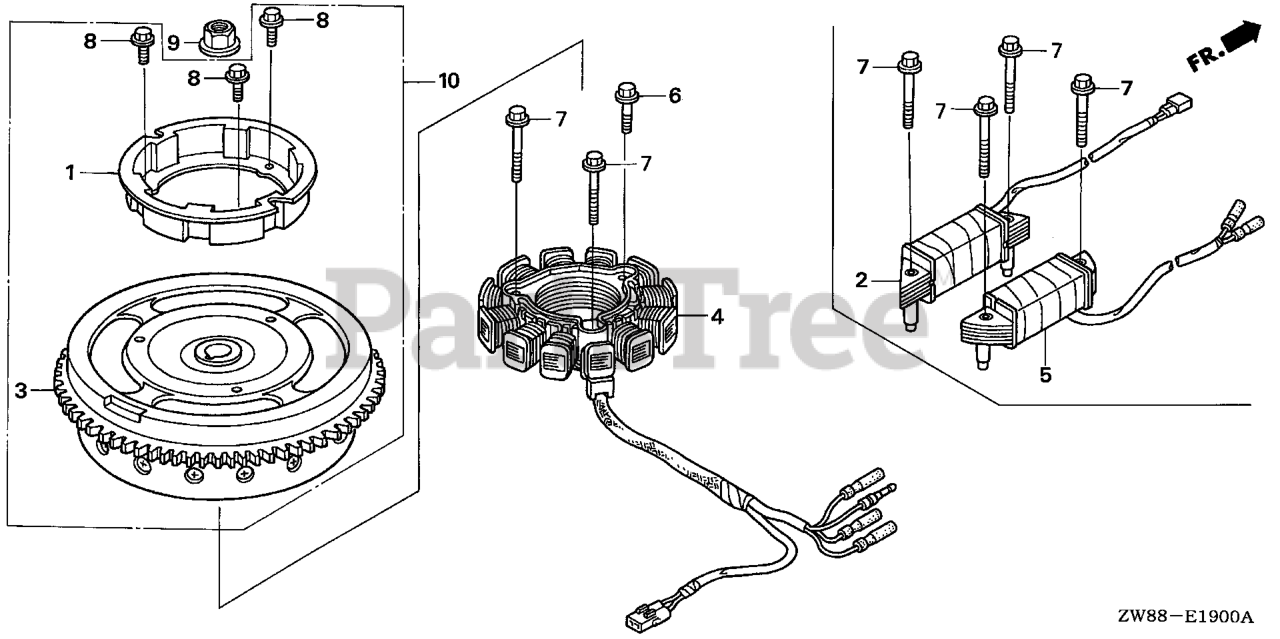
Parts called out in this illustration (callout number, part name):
1	PULLEY, STARTER
3	FLYWHEEL *TBLACK* (SELF STARTER) (BLACK)
4	COIL ASSY., CHARGE (12A)
6	BOLT (6X36) (CT200)
7	BOLT, FLANGE (6X52) (CT200)
8	BOLT, FLANGE (6X10)
9	NUT, SPECIAL (14MM)
10	FLYWHEEL *TBLACK* (SELF STARTER) (BLACK)
